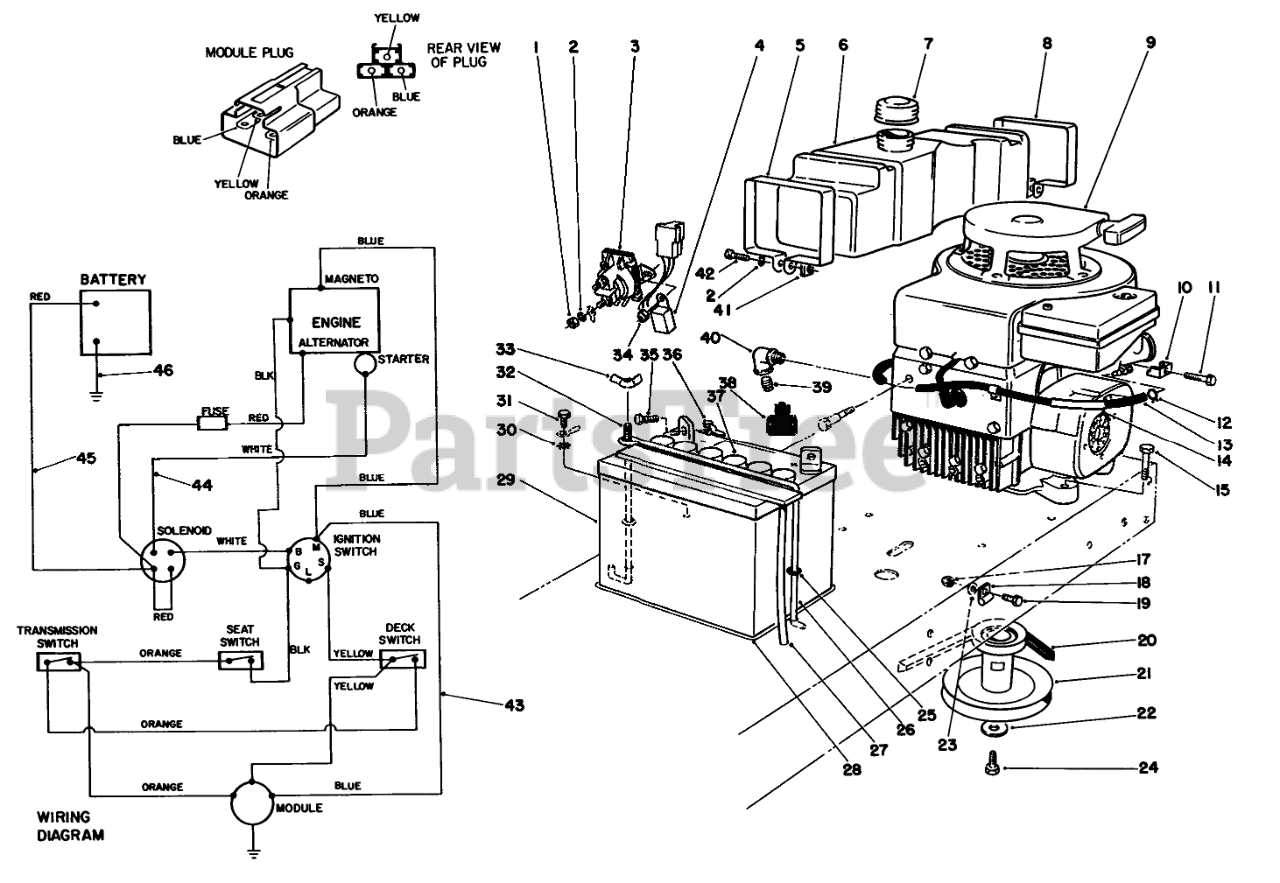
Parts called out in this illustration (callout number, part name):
1	NUT-JAM
2	WASHER-LOCK
3	SOLENOID
4	Module Interlock
5	Retainer-Front
6	TANK-5 QT GAS
7	GAS CAP ASM
8	Retainer-Rear
9	Engine-12.5 H.P. B&S
10	CLAMP-CASING
11	SCREW W ENGINE
12	CLAMP-HOSE
13	HOSE - FUEL
14	SUPPORT-FUEL LINE
15	SCREW-HH
17	NUT-LOCK, NI
18	CLAMP
19	SCREW-HH
20	V-BELT, TRACTION
21	ENGINE PULLEY ASM
22	WASHER-FLAT
23	WASHER-PLAIN
24	SCREW-HH
25	O-RING
26	HOLDDOWN-BATTERY
27	TUBE-BATT DRAIN/80-2600
28	PAD-SKID, ANTI
29	Battery
30	WASHER-LOCK, INTERNAL
31	SCREW-HWHTF
32	POST-BATTERY
33	NUT-WING
34	NUT-LOCK, NI
35	SCREW-HH
36	NUT-WING
37	CAP-BATTERY
38	BOOT-TERMINAL
39	3/8 PIPE PLUG
40	ELBOW-STREET, 90 DEG
41	NUT-SQUARE
42	SCREW-HSH
43	WIRING HARNESS
44	WIRE HARNESS
45	WIRE ASM
46	WIRE ASM(BATT/GRD.
